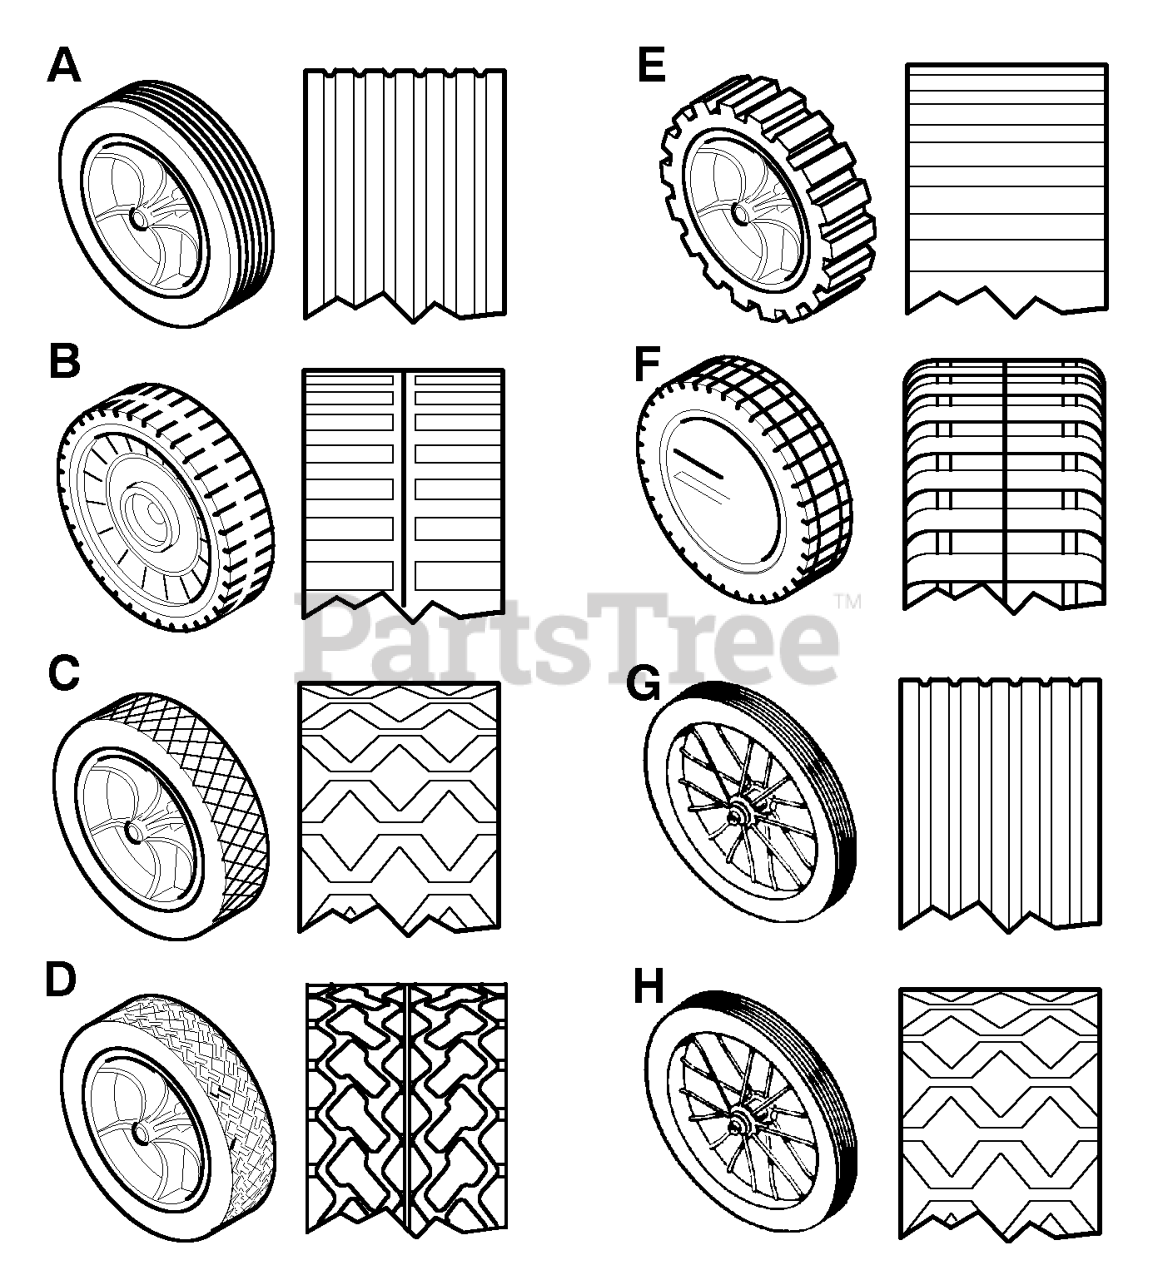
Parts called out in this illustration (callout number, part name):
A	WHEEL & TIRE ASSEMBLY, Light Gray, 8"
A	8 inch Plastic, Gray
A	8 inch Metal, White
B	7 inch Plastic, White
B	7 inch Plastic, Gray
C	6 inch Plastic, White
C	7 inch Plastic, White
C	7 inch Plastic, Gray
C	8 inch Plastic, White
C	8 inch Metal, White
D	7 inch Plastic, White
D	WHEEL & TIRE ASSEMBLY, White, 8"
D	8 inch Plastic, Gray
E	WHEEL & TIRE ASSEMBLY, White, 8"
E	8 inch Plastic, Gray
E	8 inch Metal, White
F	WHEEL & TIRE ASSEMBLY, White, 8"
F	8 inch Plastic, Gray
F	8 inch Ball Bearings, Gray
G	14 inch Spoke
G	16 inch Spoke
H	WHEEL & TIRE ASSEMBLY, 16" Spoke
